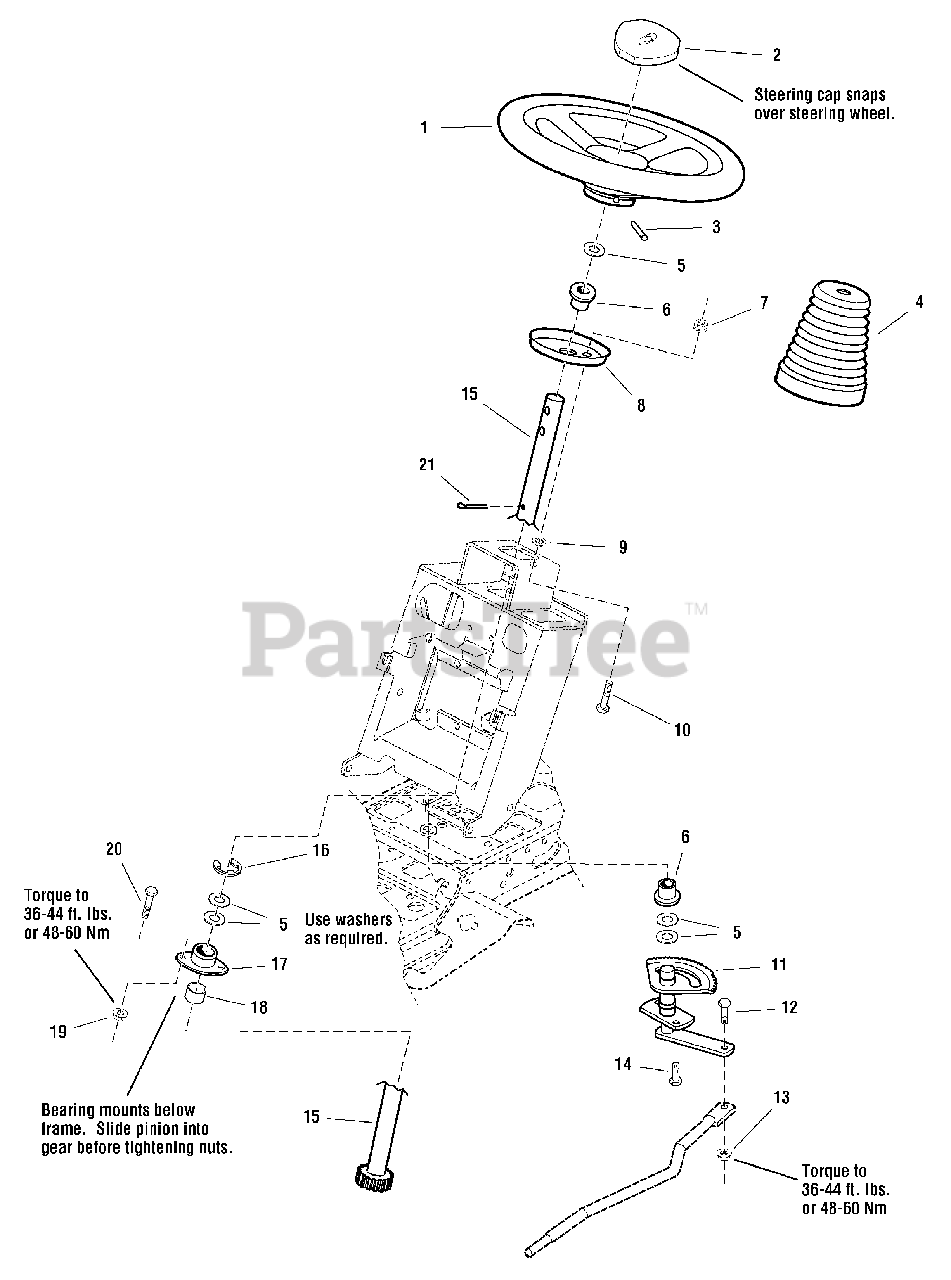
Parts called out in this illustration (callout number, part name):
1	STEERING WHEEL, Straight, Shaft
2	CAP, Steering Wheel, Simplicity
2	CAP, Steering Wheel, Plain
3	PIN, Spring, 5/16 x 2-1/2
4	COVER, Rubber, Upper Steering Shaft
5	WASHER, 3/4
6	BUSHING, 15/32 x 7/8 x 7/8, Nylon
7	NUT, Hex KEPS 5/6-18
8	PLATE, Mounting Steering
9	NUT, Push
10	CARRIAGE BOLT, 5/16-18 x 1-1/4
11	GEAR & SHAFT ASSEMBLY, Steering
12	CAPSCREW, Hex Head, 3/8-16 x 1-1/4, Black
13	NUT, Hex Flange Two-Way Lock, 3/8-16
14	CAPSCREW, Hex Washer Head Taptite, 5/16-18 x 3/4
15	SHAFT & PINION ASSEMBLY, Steering Manual
16	RING, Clipring Extension
17	BEARING, 3/4 x 1-11/16 x 13/16, 3" Long Housing
18	SPACER, 3/4 x 1-1/16 x 3/8, Powder Metal
19	NUT, Hex Flange Whiz Lock, 3/8-16, Small
20	CAPSCREW, Hex Whiz Lock Flange, 3/8-16 x 3/4, Black
21	CLIP, Hairpin
